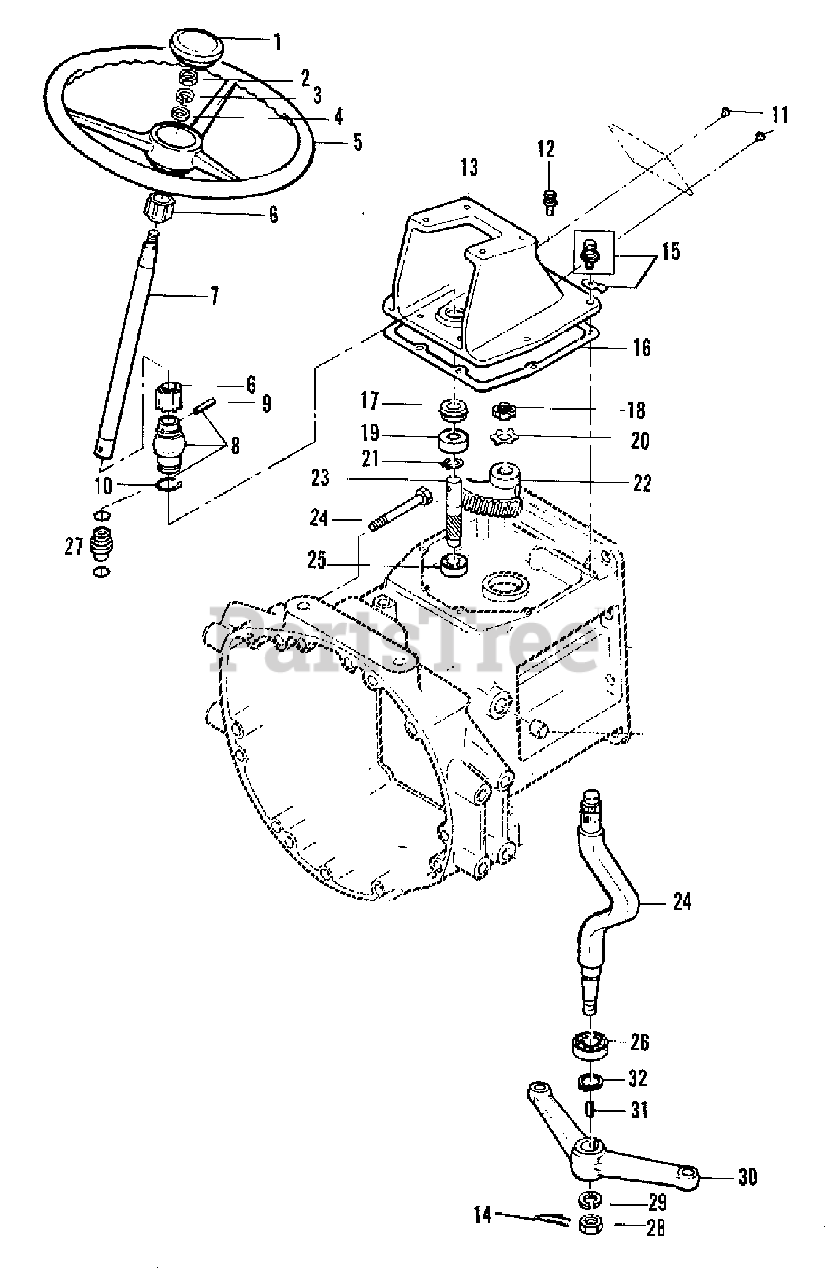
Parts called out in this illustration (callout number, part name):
1	CAP, steering wheel
3	LOCKWASHER, M12
5	WHEEL, steering
6	BUSHING, steering post
7	SHAFT, steering
8	UNIVERSAL JOINT ASSEMBLY (Incl. Items 8, 9 & 10)
11	RIVET, drive
13	BOX, joint
14	PIN, cotter
17	SEAL, oil
21	RING, M20 snap
22	GEAR, steeing
23	PINION, steering
27	SEAL, w/two rings
29	LOCKWASHER, M16
30	ARM, pitman
32	RING, M25, snap
